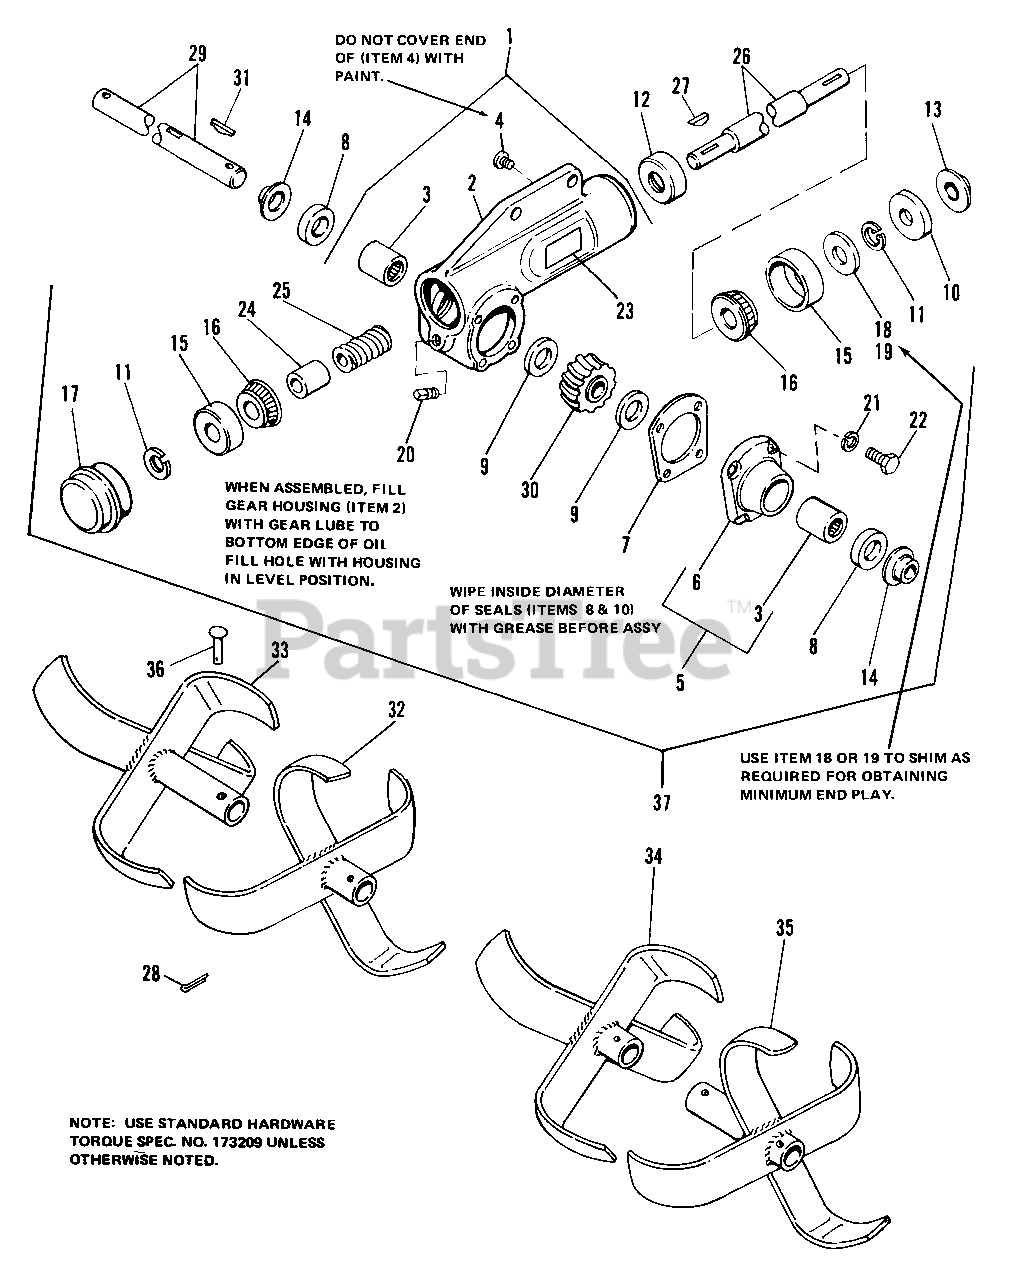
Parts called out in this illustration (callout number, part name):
1	HOUSING, BEARING & VENT ASSY
3	BEARING, Needle
5	BEARING & COVER ASSY, Needle
9	WASHER, Thrust
11	RING, Retaining
15	CUP, Bearing
16	CONE, Bearing
17	CAP, Hub
18	RING, Backing
19	RING, Backing
20	PLUG, Oil
21	LOCKWASHER, 1/4
22	CAPSCREW, Hex, 1/4-20 x 5/8
23	DECAL, Oil Fill
25	WORM, R.H.
26	SHAFT, Worm
27	KEY, Hi-Pro
28	PIN, Cotter, 1/8 x 3/4
29	SHAFT, Worm Gear
31	KEY, Woodruff
32	TINE ASSY, R.H., Inner
33	TINE ASSY, R.H., Outer
34	TINE ASSY, L.H., Inner
35	TINE ASSY, L.H., Outer
36	PIN
37	WORM DRIVE ASSY
